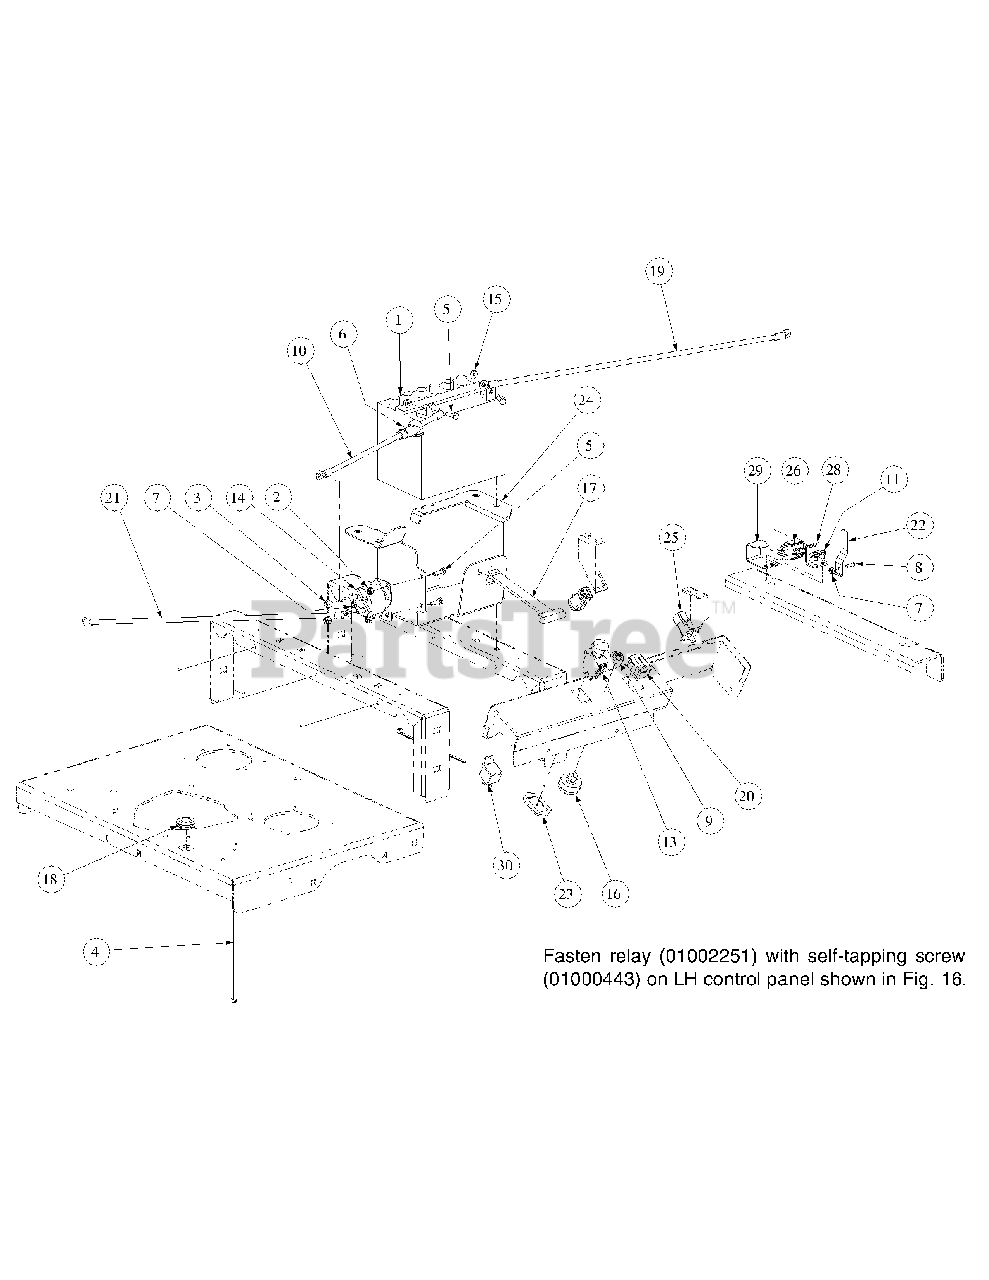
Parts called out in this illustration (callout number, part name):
1	Battery, 12V 225CCA 30 Min
2	Lock Nut w/Nylon Insert
3	Nylock Nut, 5/16-18
4	Tie, Cable, 3/16 x .05 x 7.4"
5	Screw, Hex, Cap, 1/4-20 x .75
6	Boot, 1" OD Rubber Battery-PST, Red
7	Nut, Lock, Nylon Insert, #10-32
8	Screw, Phillips Head, Machine, 10-32 x 5/8
9	Nut, W/Cap, 5/8-32 Ignition
10	Cable, Battery, Red, 15"
11	Screw, TT, 1/4-20, 0.5, Hex Index Washer
12	Hourmeter, Harness
13	Switch, Electric, PTO
14	Solenoid Magnetic Switch
15	Hex Flange Lock Nut, 1/4-20
16	Switch, Ignition, 6 Pin
17	Strap, Battery
18	Grommet, .75 ID
19	Cable, Battery Black, 28"
20	Meter, Hour
21	Cable, Battery Red, 32"
22	Spring Retainer
23	Bracket, PTO Switch Retainer
24	Mount Bracket, Battery
25	Switch, Safety N.O./N.C.
26	Switch, Plunger
27	Harness Assembly
28	Bracket, Plunger Switch
29	Clamp, Plunger Switch
30	Relay, 12V 40A
